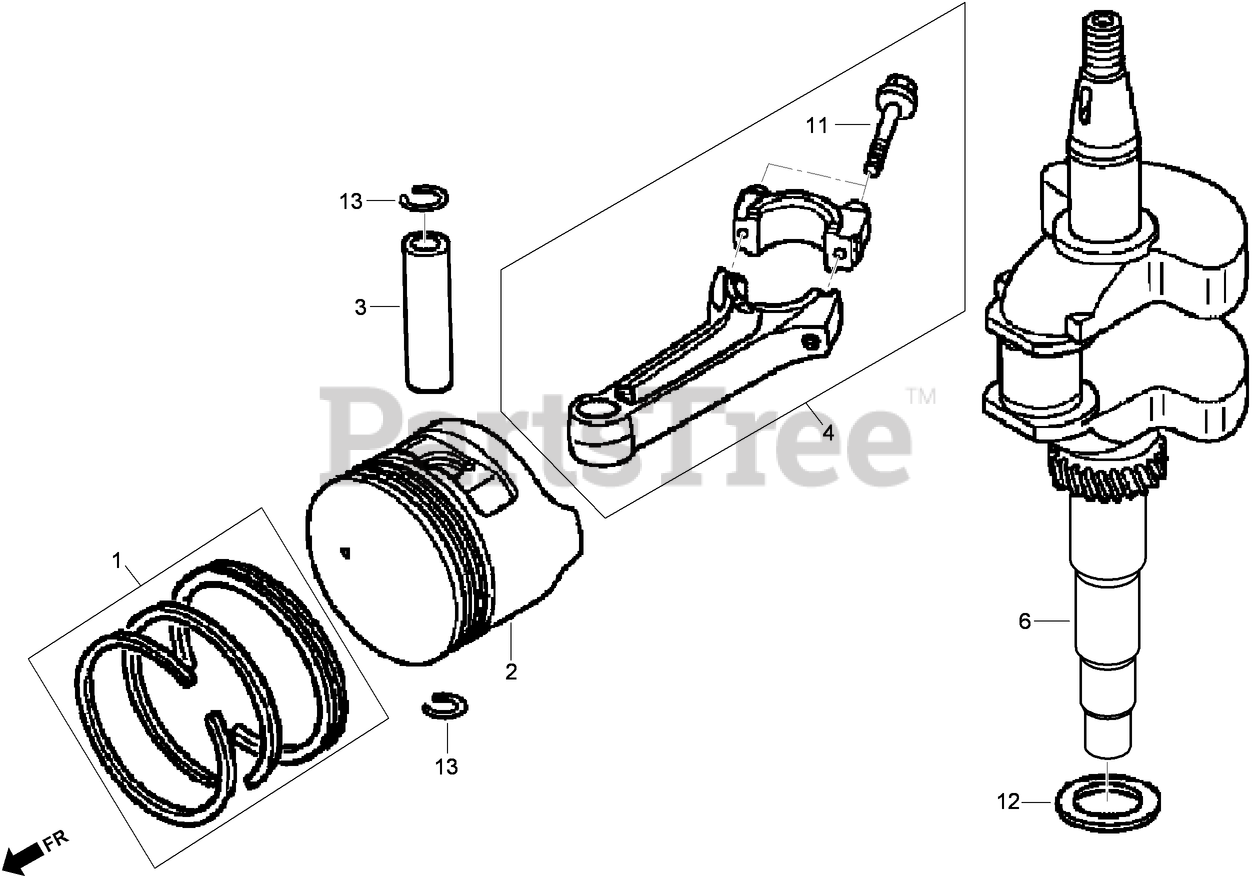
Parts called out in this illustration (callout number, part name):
1	PISTON RING SET (STD) (TEIKOKU)
1	RING SET-PISTON (STD) (NIPPON)
1	PISTON RING SET (STD) (RIKEN)
1	PISTON RING SET (O S 0.25) (TEIKOKU)
1	RING SET-PISTON (O S 0.25) (NIPPON)
1	PISTON RING SET (O S 0.25) (RIKEN)
1	PISTON RING SET (O S 0.50) (TEIKOKU)
1	RING SET-PISTON (O S 0.50) (NIPPON)
1	PISTON RING SET (O S 0.50) (RIKEN) (Engine Serial No. From 1036456)
1	PISTON RING SET (O S 0.75) (TEIKOKU)
1	RING SET-PISTON (0.75) (NIPPON)
1	PISTON RING SET (0.75) (TEIKOKU)
1	PISTON RING SET (0.75) (RIKEN)
2	PISTON (STD)
2	PISTON (STD) (JIALING-HONDA)
2	PISTON (O S 0.25)
2	PISTON (O S 0.50)
2	PISTON (0.75)
3	PIN-PISTON
4	CONNECTING ROD ASM
6	CRANKSHAFT
11	BOLT-ROD, CONNECTING
12	WASHER-THRUST (25.6 mm)
13	CLIP-PIN, PISTON (18 mm)
